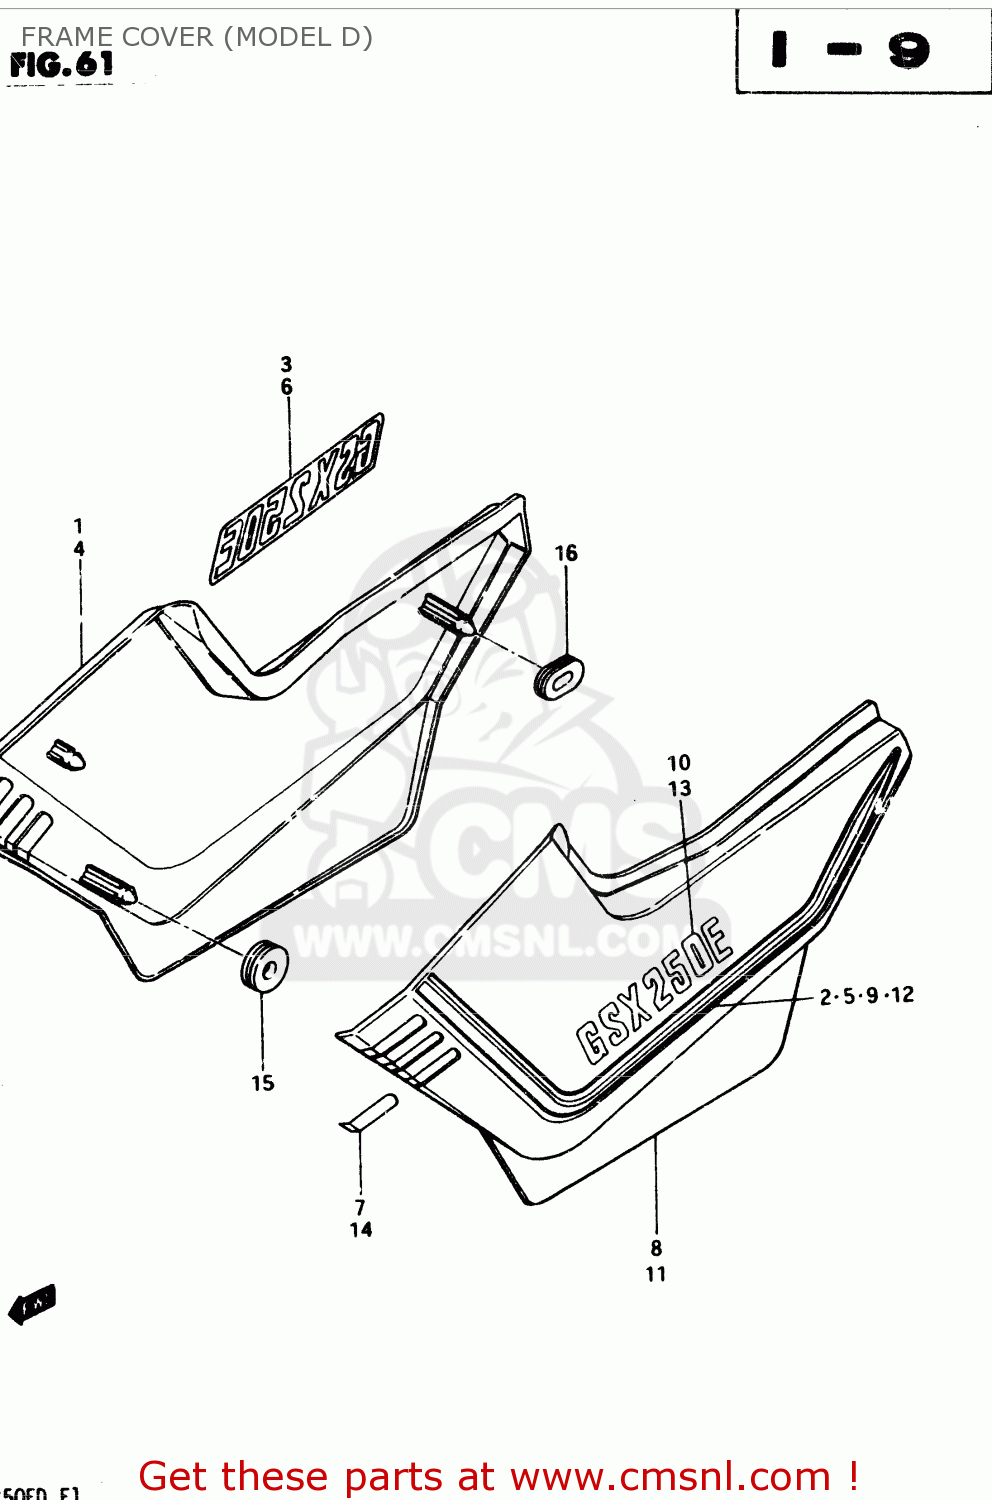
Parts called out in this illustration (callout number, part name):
1	COVER, FRAME RH (RED)
2	TAPE SET, FRAME COVER RH
3	EMBLEM, LH
4	COVER, FRAME RH (SILVER)
5	TAPE SET, FRAME COVER RH
6	EMBLEM
7	LABEL,FRAME COVER DENT
8	COVER,FRAME,L
9	TAPE SET, FRAME COVER LH
10	EMBLEM, LH
11	COVER, FRAME LH (SILVER)
12	TAPE SET, FRAME COVER LH
13	EMBLEM
14	LABEL,FRAME COVER
15	CUSHION
16	CUSHION
